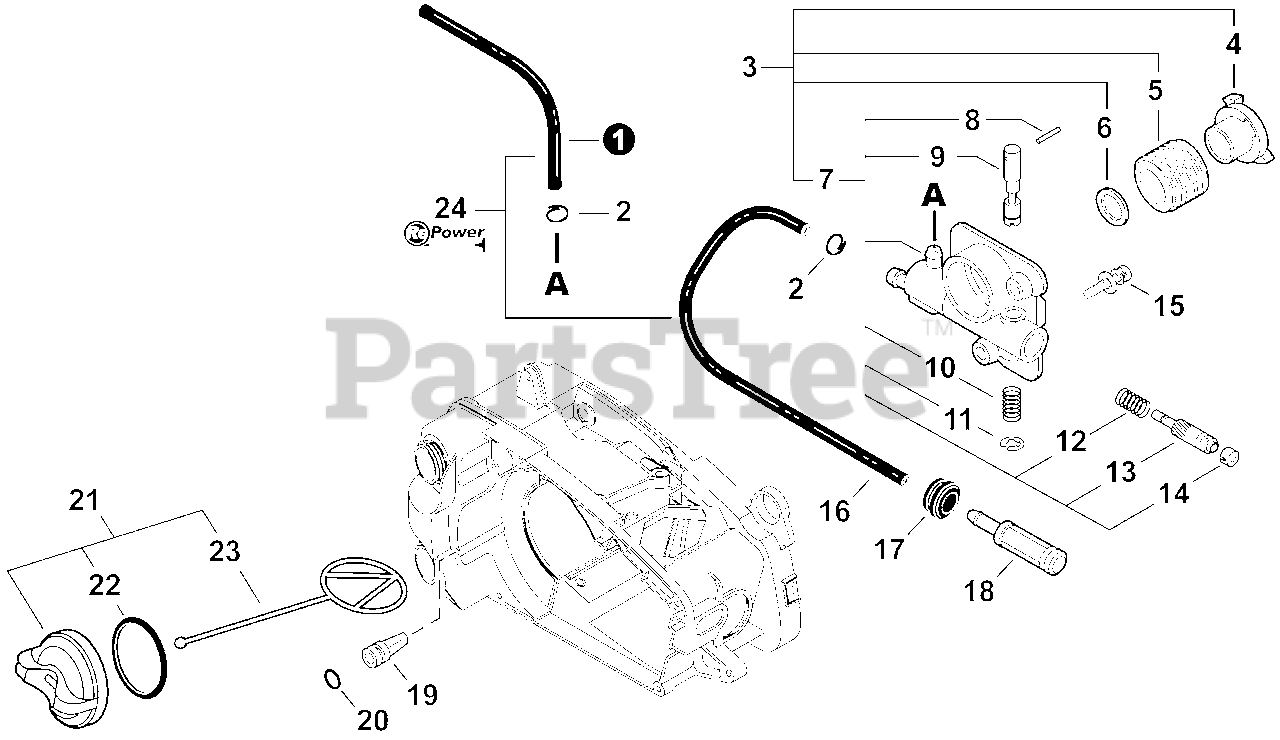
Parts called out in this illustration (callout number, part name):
1	PIPE 3×6×90 MM
2	CLIP Ø6.5 MM
3	AUTO-OILER ASSY
4	COLLAR 10
5	GEAR, WORM
6	WASHER 10.5×17.4×1.8
7	AUTO-OILER ASSY
8	PIN, SPRING
9	ADJUSTER, OILER
13	PLUNGER ASSY
14	CAP, OIL PUMP
15	SCREW 4×12
16	PIPE 3×6×160
17	GROMMET
18	FILTER, OIL
19	VENT ASSY
20	O-RING S-4
21	CAP ASSY - BLACK
22	O-RING 18
23	CONNECTOR, CAP L= 60 MM
24	BULK PIPE - 3×6 MM BLACK (4 PIECES×2 M)
